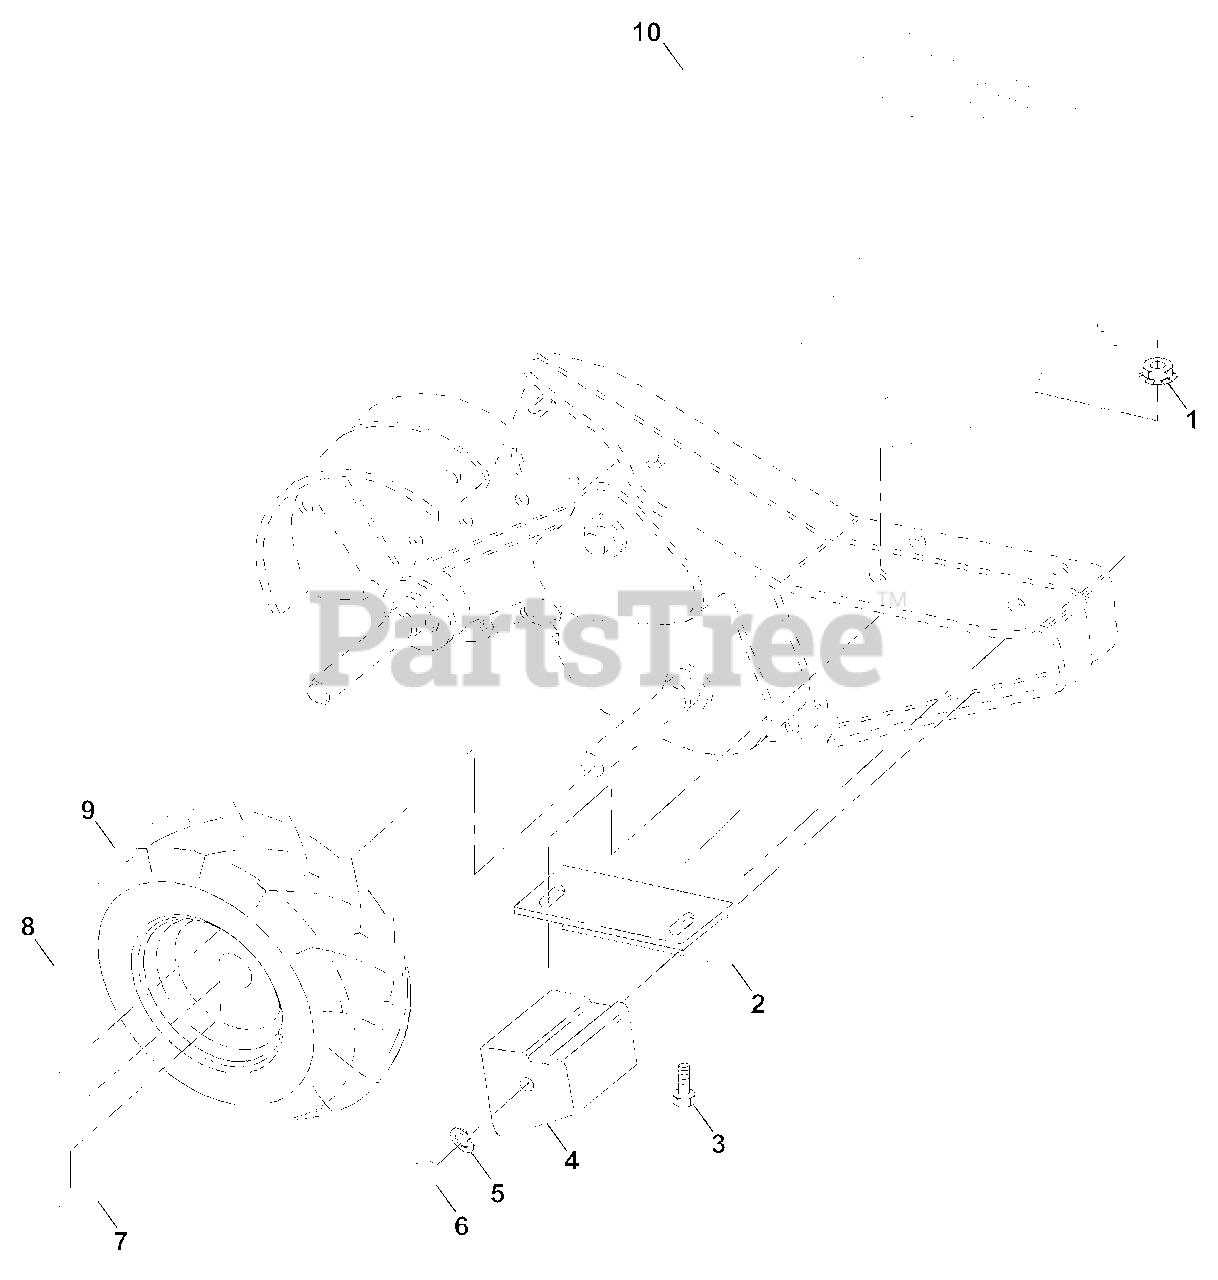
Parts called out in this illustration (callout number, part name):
1	Nut, Keps 5/16-18
2	Bracket, Reinforcement
3	Bolt, Hex 5/16-18 x 1-1/2
4	Counter Weight, R.H.
5	Washer, Lock 3/8
6	Nut, Hex 3/8-16
7	Clip, Hairpin
8	Rivet, Drilled
9	Tire Valve
10	Engine, Briggs & Stratton
